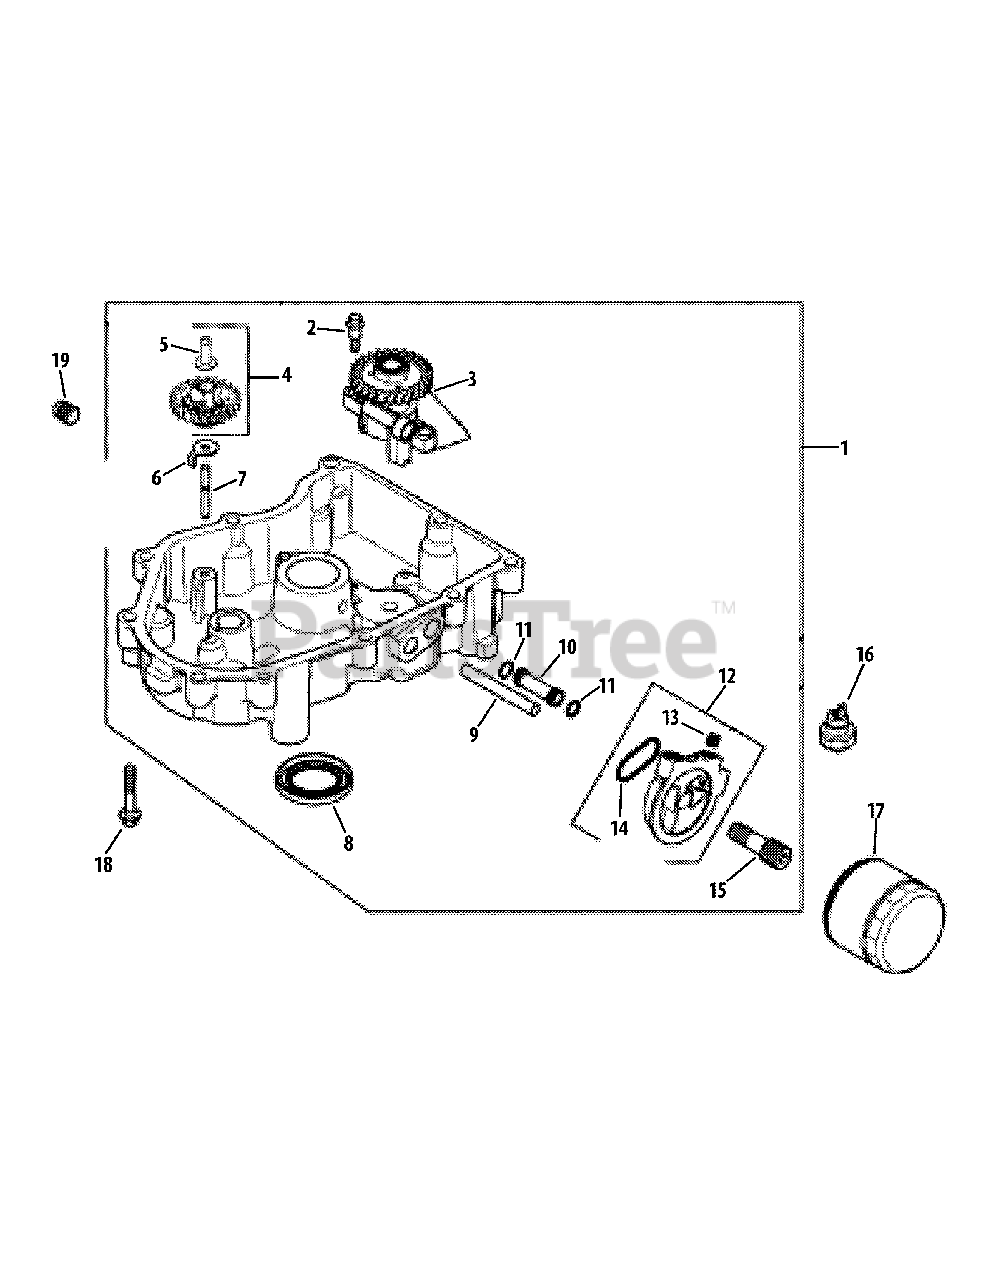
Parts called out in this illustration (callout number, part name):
1	Oil Pan Assembly
2	Screw, M6 x 6.5
3	Oil Pump Assembly
4	Governor Gear Kit w/ Pin
5	Governor Regulating Pin
7	Governor Gear Shaft
8	Oil Seal, 2.38 x 1.45
9	Oil Feed Tube (Filter to Pan)
10	Oil Feed Tube (Pan to Filter)
11	Oil Pick-Up O-Ring
12	Adapter Oil Filter Kit
13	Pipe Plug, 1.8
14	Oil Filter Adapter O-Ring
15	Oil Filter Nipple
16	Oil Pressure Switch
18	Flange Screw, M8 x 1.25 x 45
19	Square Head Pipe Plug, 3.8
